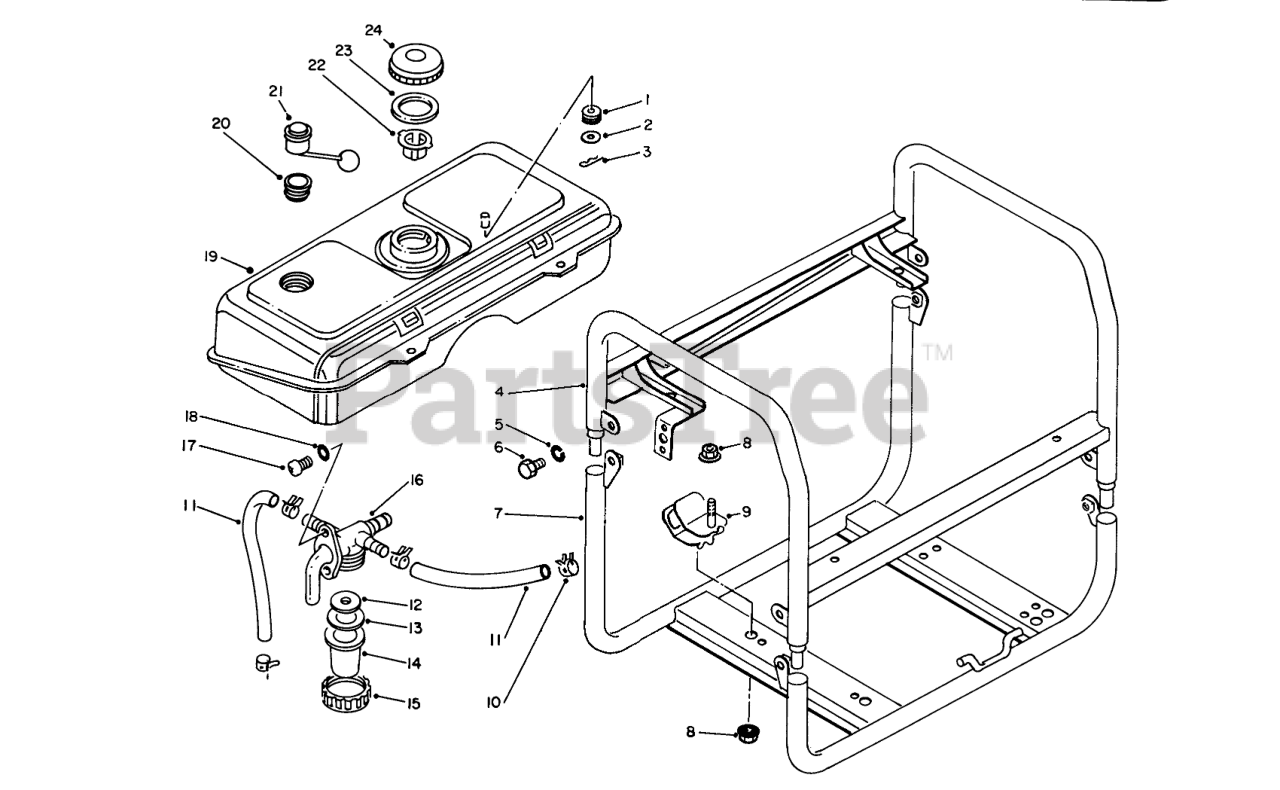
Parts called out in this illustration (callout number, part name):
1	CUSHION
2	WASHER
4	Frame-Upper
5	WASHER-LOCK
7	Frame-Lower
9	Engine Mount
12	FILTER
13	GASKET
16	Cock Assembly-Fuel (Incl. Ref. #12-15)
17	Screw
18	Lockwasher
19	Fuel Tank
20	Gasket
21	Gauge Assembly-Fuel (Incl. Ref. #20)
22	FILTER
23	GASKET
24	Cap (Incl. Ref. #23)
